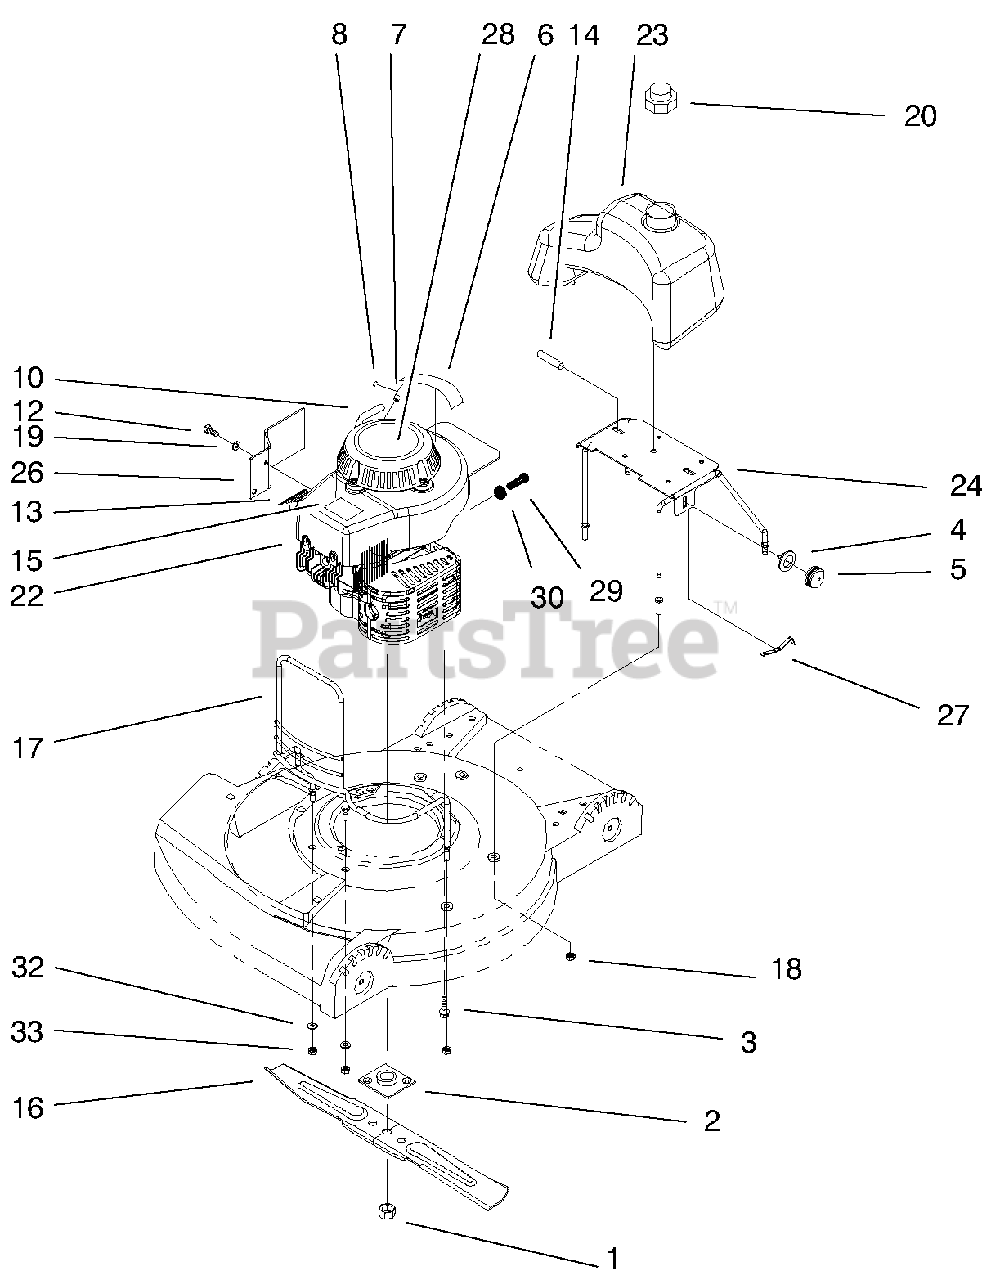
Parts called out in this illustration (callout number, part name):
1	Nut-Blade
2	Plate & Collar ASM
3	Screw-Sems
4	Body-Primer
5	Bulb-Primer
6	Decal-Fuel Mix
7	Rope Stop
10	Line-Gas
12	Screw-HH
13	Spring-Compression
14	Plug-Cap
15	Decal-Lawn Boy
16	Blade-21" Whirl
17	Muffler-Guard
18	Nut-Lock
19	Washer-Lock/Sp
20	Assembly-Cap, Fuel/Oil
22	Engine ASM For Service
23	Tank-Fuel
24	Tank Brkt ASM
26	Guard-Brake
28	Decal-Recoil
29	Screw-Sems
30	Nut-Hex
32	Hood Pivot Washer
33	Nut-Lock
